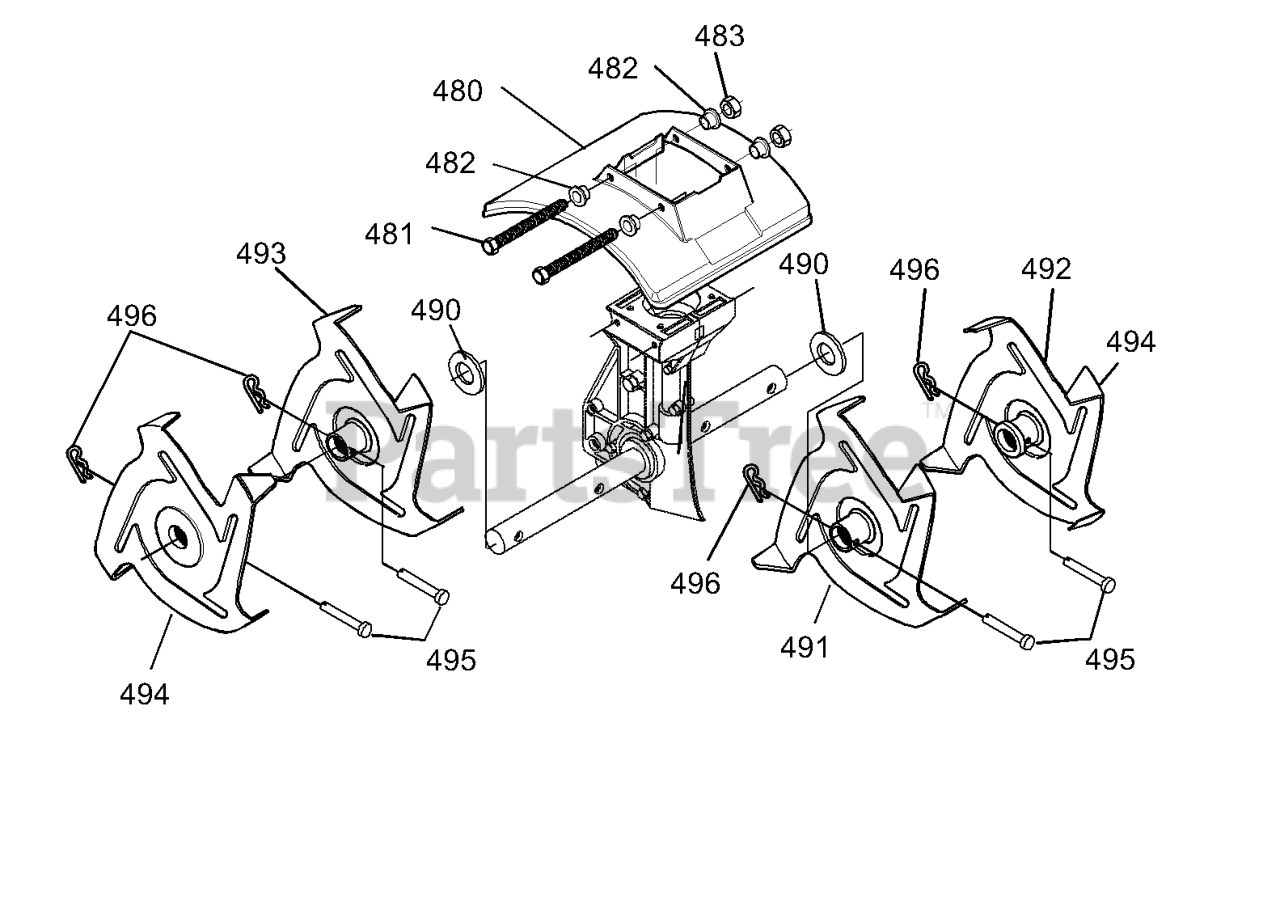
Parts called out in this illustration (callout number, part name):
480	Shield, Tine
481	Screw, 1/4-20x5.50
482	Spacer, Flange
483	Nut, 1/4-20
490	Washer, Felt
491	Tine Assy. Inner LH
492	Tine Assy. Outer LH
493	Tine Assy. Inner RH
494	Tine Assy. Outer RH
495	Clevis Pin
496	Hair Pin
